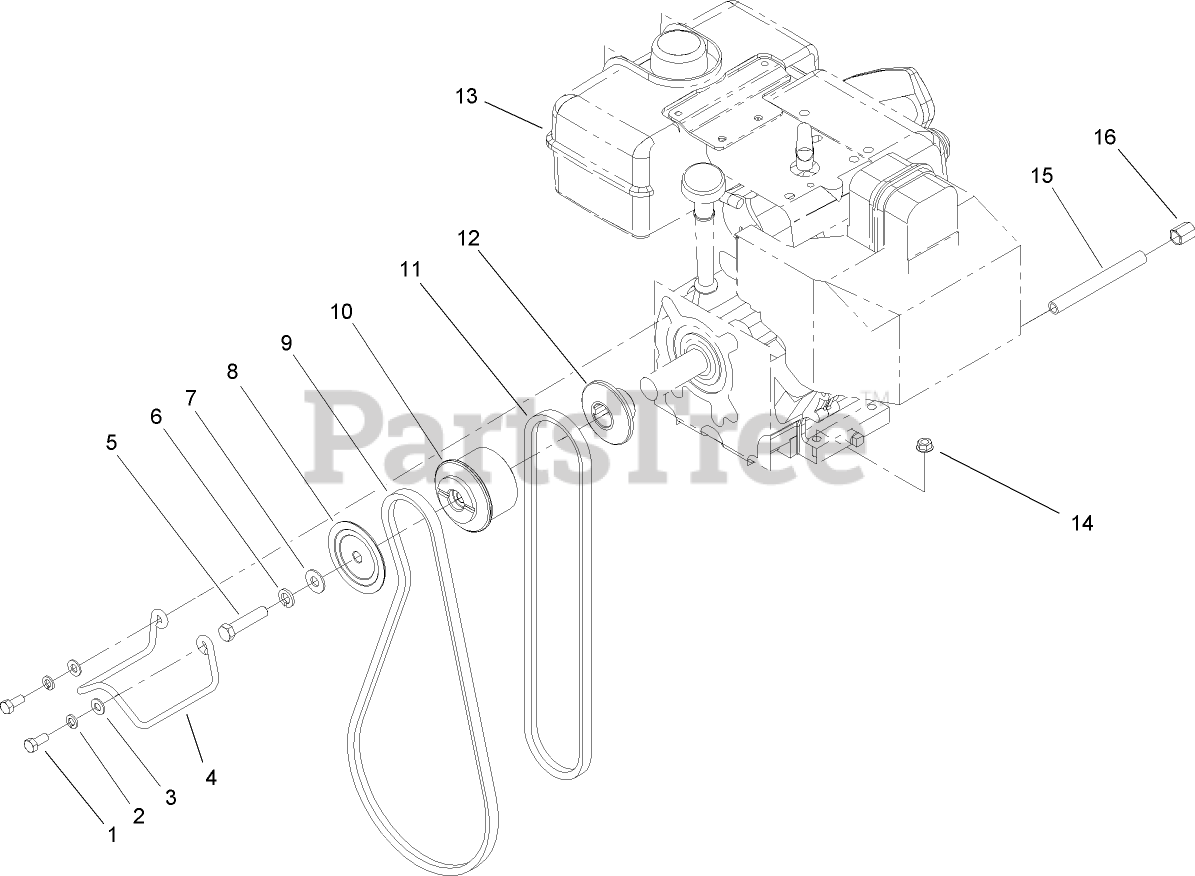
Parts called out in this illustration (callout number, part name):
1	SCREW-HH
2	WASHER-LOCK
3	WASHER-PLAIN
5	SCREW-HH
6	WASHER-LOCK
7	WASHER-FLAT
8	SHEAVE-HALF, IMPELLER
9	BELT-V
10	PULLEY-ENGINE, CENTER
11	V BELT-TRACTION
12	SHEAVE-HALF, TRACTION
13	Loose Parts Package
14	NUT-HF
15	NIPPLE-PIPE
16	CAP-PIPE
